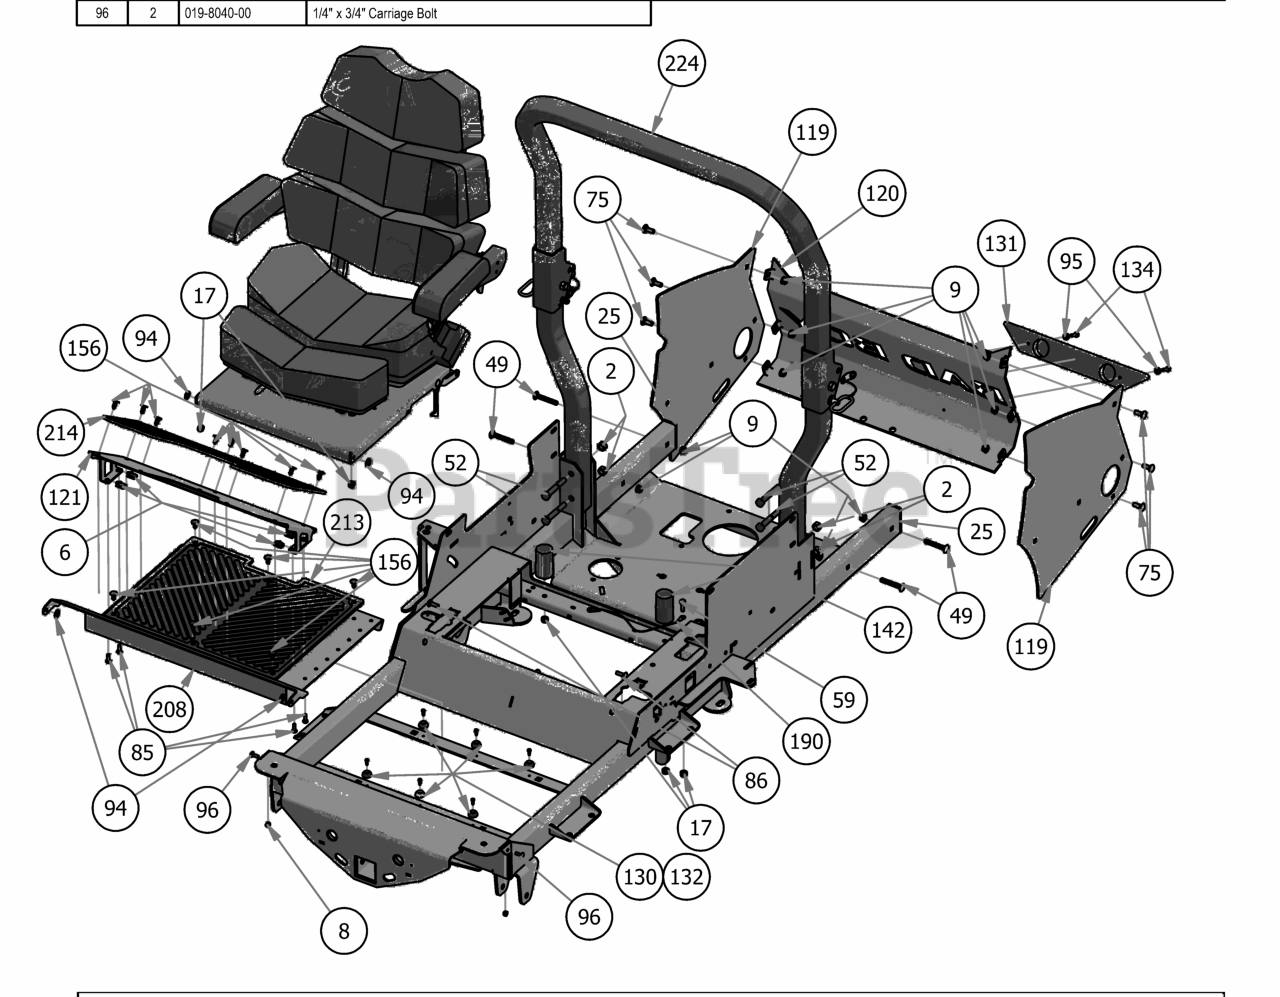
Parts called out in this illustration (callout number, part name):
2	1/2" Center Lock Nut
6	1/4-20 Cage Nut
8	1/4-20 Hex flang lock nut
9	3/8" Nylock Flange Nut
17	5/16-18 Nylon Flange Nut
25	1 1/2 x 3 Frame Plug
49	3/8" x 2 1/2" Carriage Bolt
52	1/2-13 X 3.25 Hex Bolt - Grade 5
53	5/16"-18 x 1/2 GR5 Hex bolt zink
59	5/16" x 1" Bolt
62	1/4" x 1/2" BS C/S 18-8 SS
75	3/8" x 1" Carriage Bolt
85	1/4" x 3/4" Hex Bolt
86	5/16" x 1" Carriage Bolt
94	.360 ID Plastic Washer
95	1/4" Flat Washer
96	1/4" x 3/4" Carriage Bolt
119	2019 Rouge Rear Cover Side Plate
120	2019 Vertical Rear Cover Tailgate Plate
121	2019 Outlaw Adjustable Foot Plate
130	Button Bumper
131	2017 XP Bumper
132	#10 x 1/2" Self Tapping Screw
134	1/4 x 1 Hex Head Tek screw
142	2019 Bad Boy X Cylindrical Seat Mount
156	Ratchet Fastener
190	Seat Cable
204	2019 Veritical Suspension Frame
208	2019 Outlaw Floorboard
213	OUTLAW2019_FLOORMAT
214	FLOORMAT_OUTLAW_2019
224	2019 2X2 Folding ROPS
